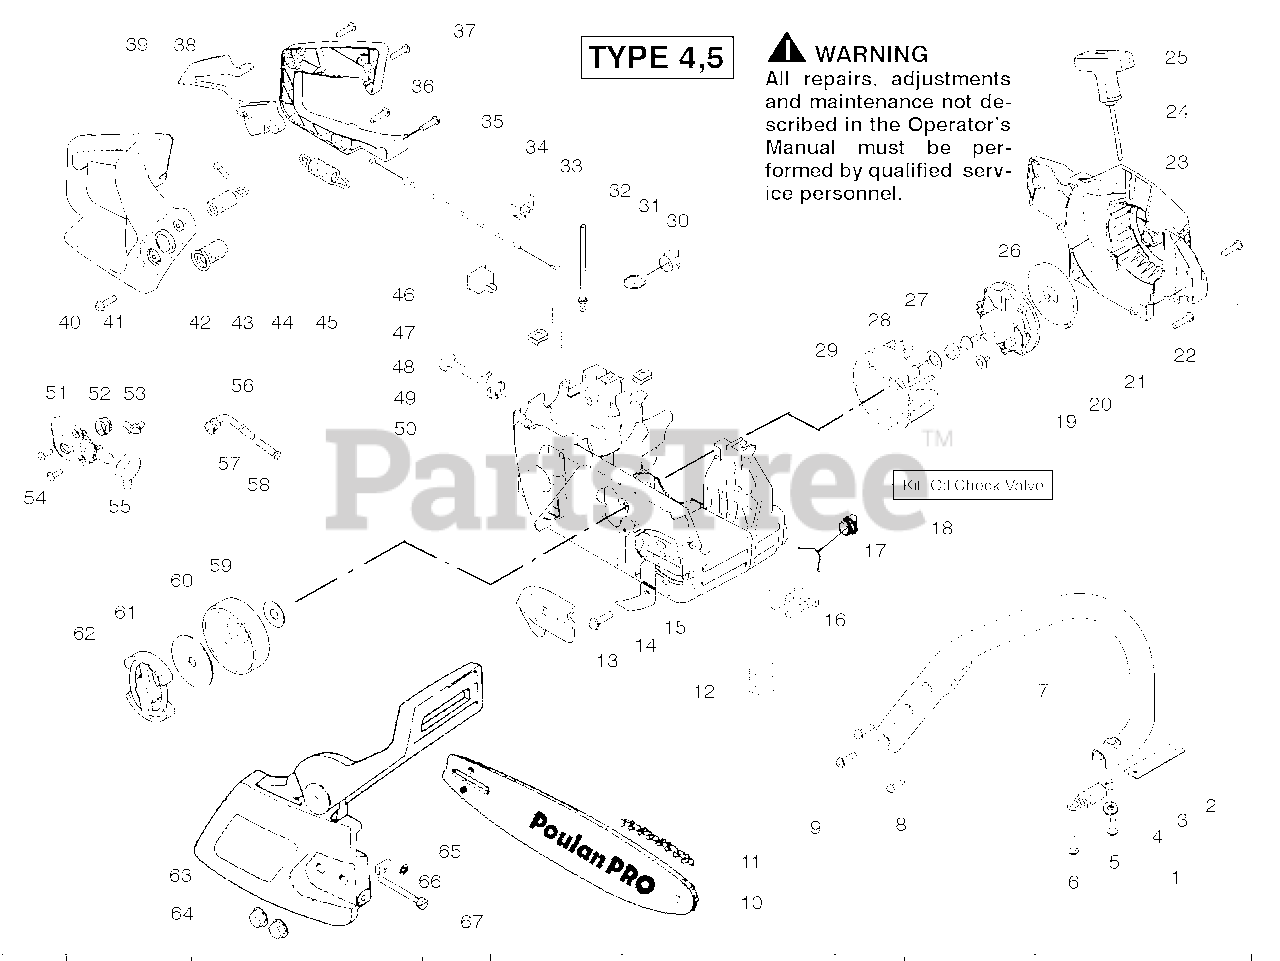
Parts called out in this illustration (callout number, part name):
1	Assy.- Isolator
2	Limiter Strap
3	Spring- Isolator
4	Washer
7	Front Handle
10	Bar-18" "Quick Adjust"
11	Chain-18"
13	Plate-Bar Mounting
15	Chain Catcher
17	Oil Cap Ass’y.
18	Kit-Oil Check Valve
19	Nut- Flywheel
21	Starter Pulley
25	Starter Handle
26	Recoil Spring
28	Washer- Flywheel
29	Assy- Flywheel
30	Fuel Cap Ass’y.
31	Fitting- fuel line
32	Kit-Fuel line (large)
33	Grommet-Cable
34	Cable-Throttle
35	Cover-Rear Handle
38	Throttle Lockout
39	Trigger-Throttle
40	Handle - Rear
42	Assy. Isolator - lower
43	Kit- Isolator (Upper)
45	Spring- Isolator
47	Nut- "U"-Type
50	Assy-Chassis
51	Kit - Oil Pump
52	Gear-Worm Spring
53	Elbow-Oil Pickup
56	Assy-Oil Pick-up
57	Pick-up Oiler
59	Washer-Thrust
60	Assy.-Clutch Drum w/bearing
61	Washer-Clutch
63	Assy-Chain Brake
64	Nut-Bar Mounting
65	Pin-Bar Adjust
66	Retainer-Bar Adjust
67	Kit-Bar Adj.
